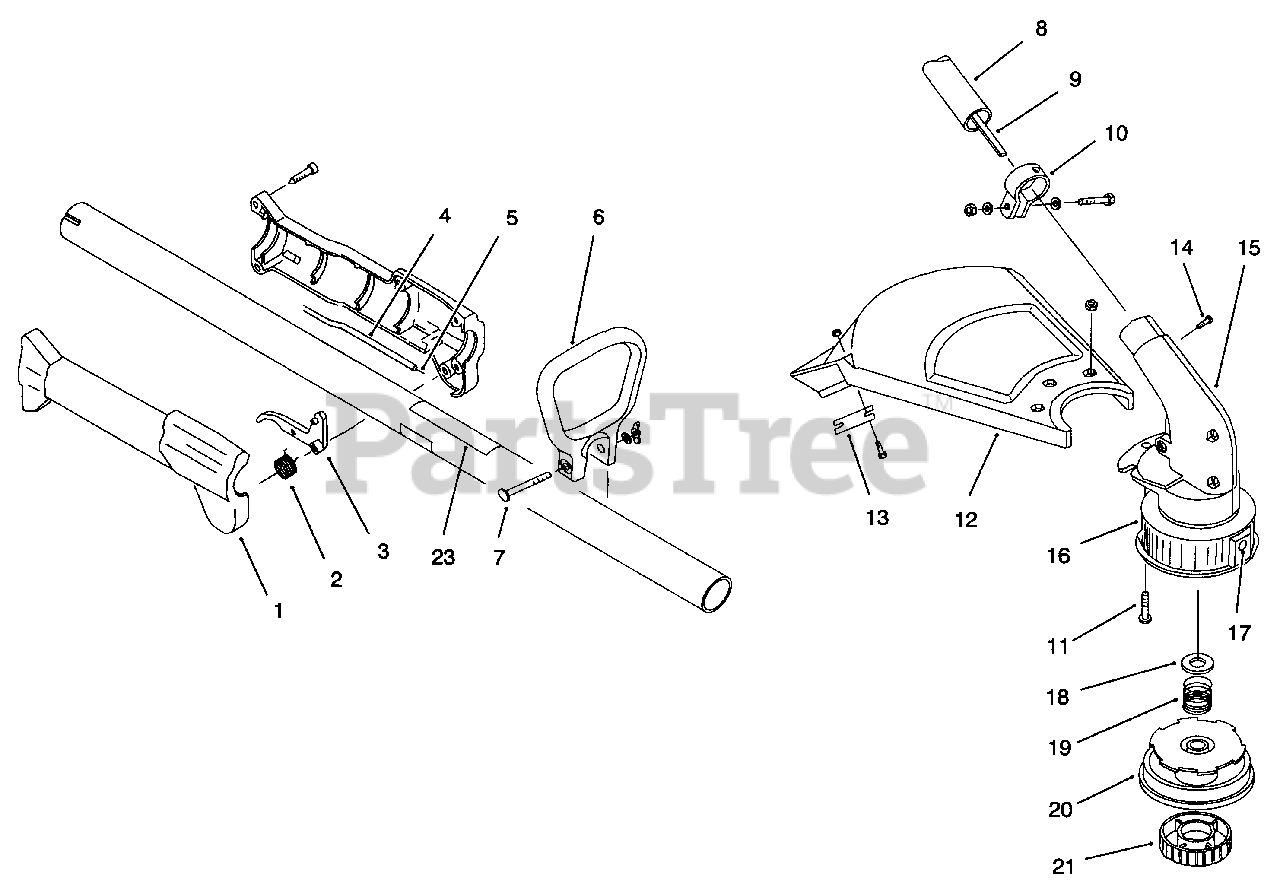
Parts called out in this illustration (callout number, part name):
1	Throttle Housing & Trigger Asm.
2	Throttle Trigger Spring
3	Throttle Trigger
4	Throttle Cable Housing Asm.
5	Throttle Cable
6	D-Handle
7	D-Handle Hardware Asm.
8	Drive Shaft Housing Asm.
9	Flexible Drive Shaft
10	Lower Clamp Asm.
11	Guard Mounting Screw Asm.
12	Guard and Blade Asm.
13	Blade Asm
14	Anti-Rotation Screw
15	Gearbox Asm.
16	Outer Spool and Eyelet Asm
18	Retainer
20	Inner Reel
21	Bump Head Knob Asm.
23	Decal-Safety Symbols
